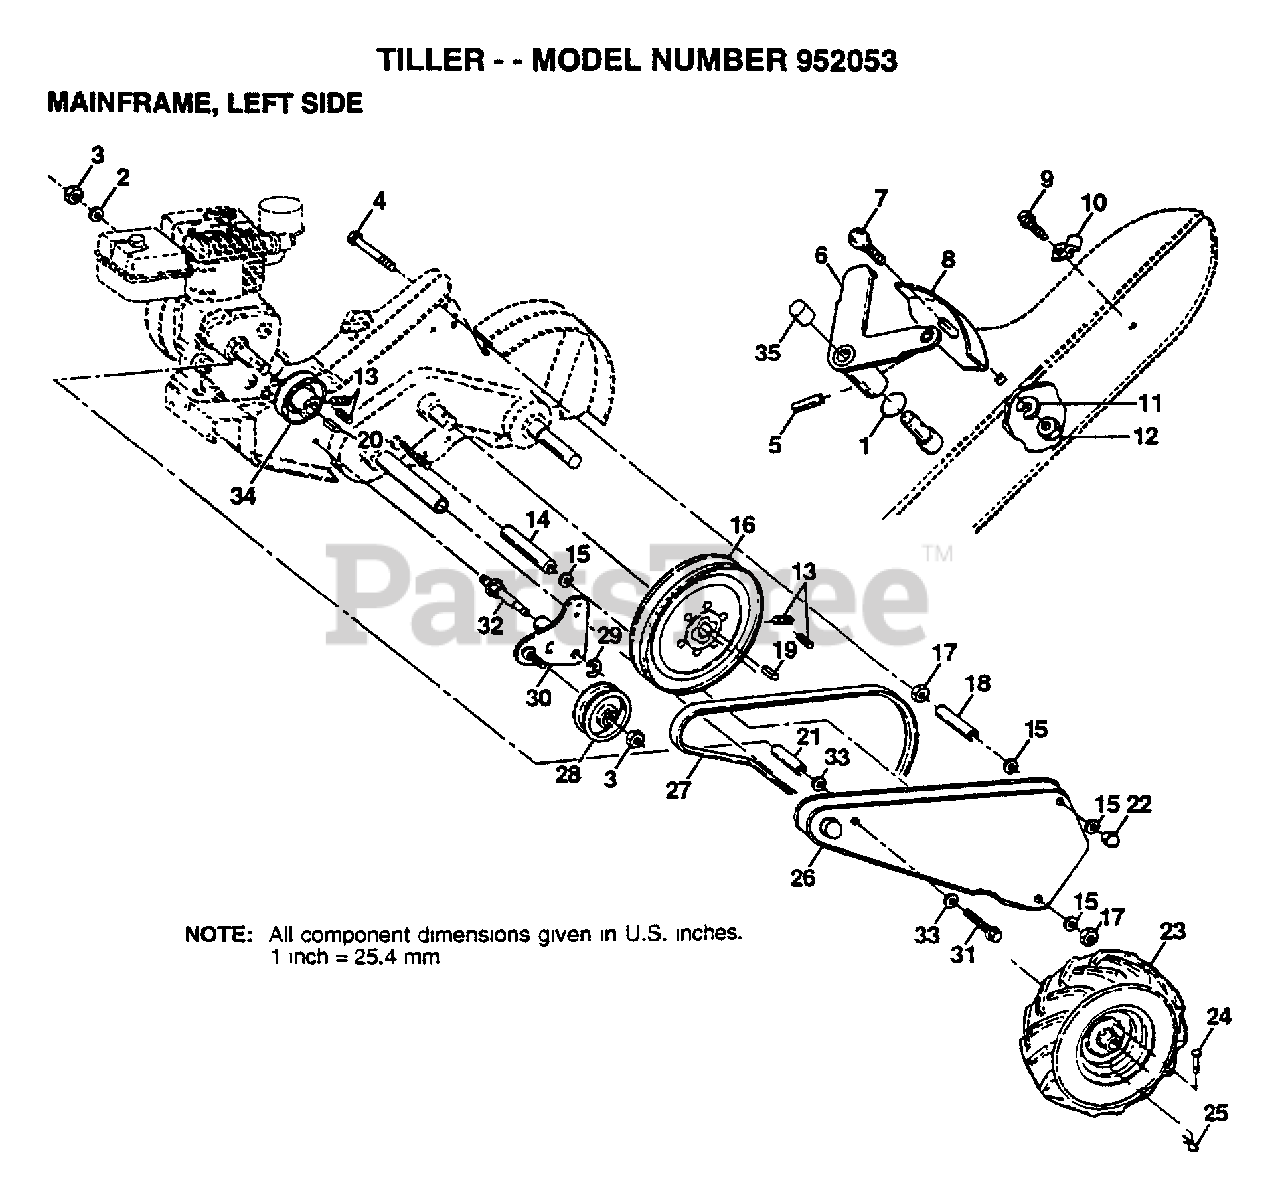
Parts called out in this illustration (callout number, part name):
1	O-RING TI
2	LOCKWASHER
3	NUT.HEX.3/8-16UNC
4	BOLT TI
6	LEVER ASM CRT
7	BOLT
8	PANEL TI
10	CONDIUT CLIP T
11	LOCKWASHER
13	SET SCREW
14	SPACER TI
15	WASHER
16	"SHEAVE 10"" CRT"
17	NUT.HEX.5/16-18
18	SPACER TI
19	KEY T
20	KEY TI
21	SPACER.SPLIT
22	NUT TI
23	TIRE TI
24	RIVET.PAN HD.1.75
25	SPRING.RETAINER
26	GUARD BELT RED
27	BELT.DRIVE
29	KLIP RING
31	BOLT1/2-20UNF2.75
32	SHAFT.IDLER
34	SHEAVE CRT
35	CAP PLUNGER BLACK
